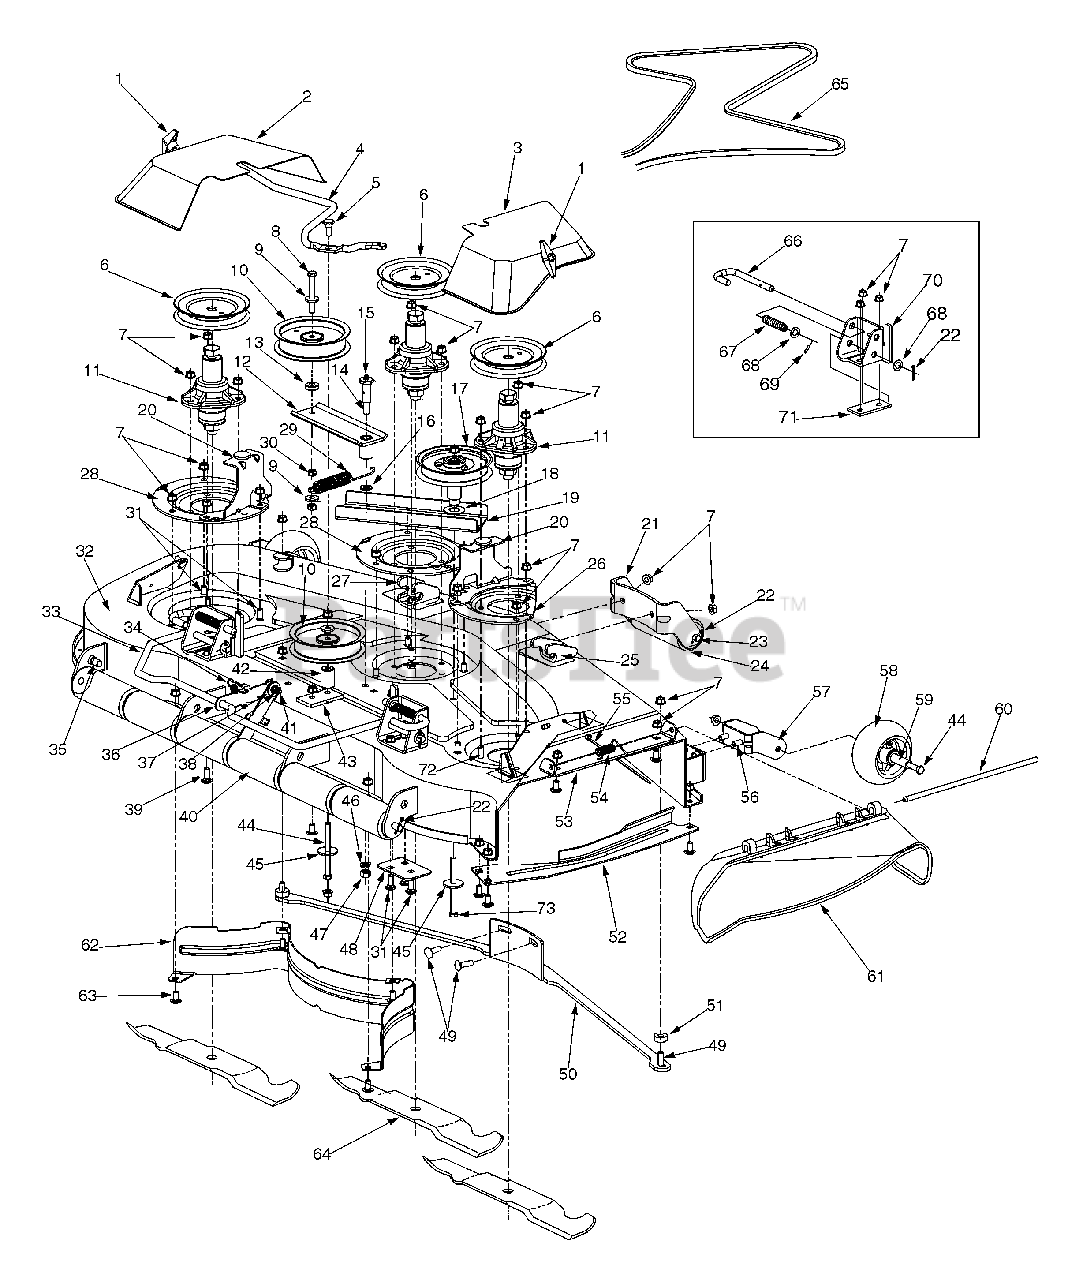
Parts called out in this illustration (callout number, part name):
1	Wingnut Knob
5	Shoulder Screw 3/8-16
6	Pulley
7	Flange Lock Nut 3/8-16
8	Hex Cap Screw 3/8-16 x 3.0
9	Flat Washer .385 ID x 1.0 OD
10	Idler Pulley 5.0
11	Deck Spindle Ass'y
12	Idler Bearing Arm Ass'y
13	Spacer
14	Shoulder Bolt
15	Grease Fitting
16	Flat Washer .469 ID x .875 OD
17	Idler Pulley Ass'y 5.0
18	Flat Washer.76 ID x 1.59 OD
20	Front End Deck Bracket LH
22	Cotter Pin
23	Roller Pin
24	Roller
29	Extension Spring
30	Lock Nut 3/8-16
31	Carriage Bolt 3/8-16
34	Extension Spring .50 OD x 2.51 Lg
35	Pin Roller
38	Flange Lock Nut 5/16-18
39	Carriage Bolt 3/8-16
40	Roller
41	Shoulder Screw
42	Spacer
45	Flat Washer
46	Lock Washer 7/16
47	Hex Nut 7/16-14
52	Finger Guard
53	Bracket
54	Torsion Spring
55	Cable Tie
56	Hex Cap Screw 3/8-16 x .860
59	Spacer
60	Hinge Pin
61	Deflector Chute
62	Inner Baffle
63	Carriage Bolt 3/8 - 16
64	Blade
66	Support Pin
67	Compression Spring
68	Flat Washer .536 ID x .93 OD
69	Spring Pin
73	Hex Cap Screw 3/8-16 x 4.5
